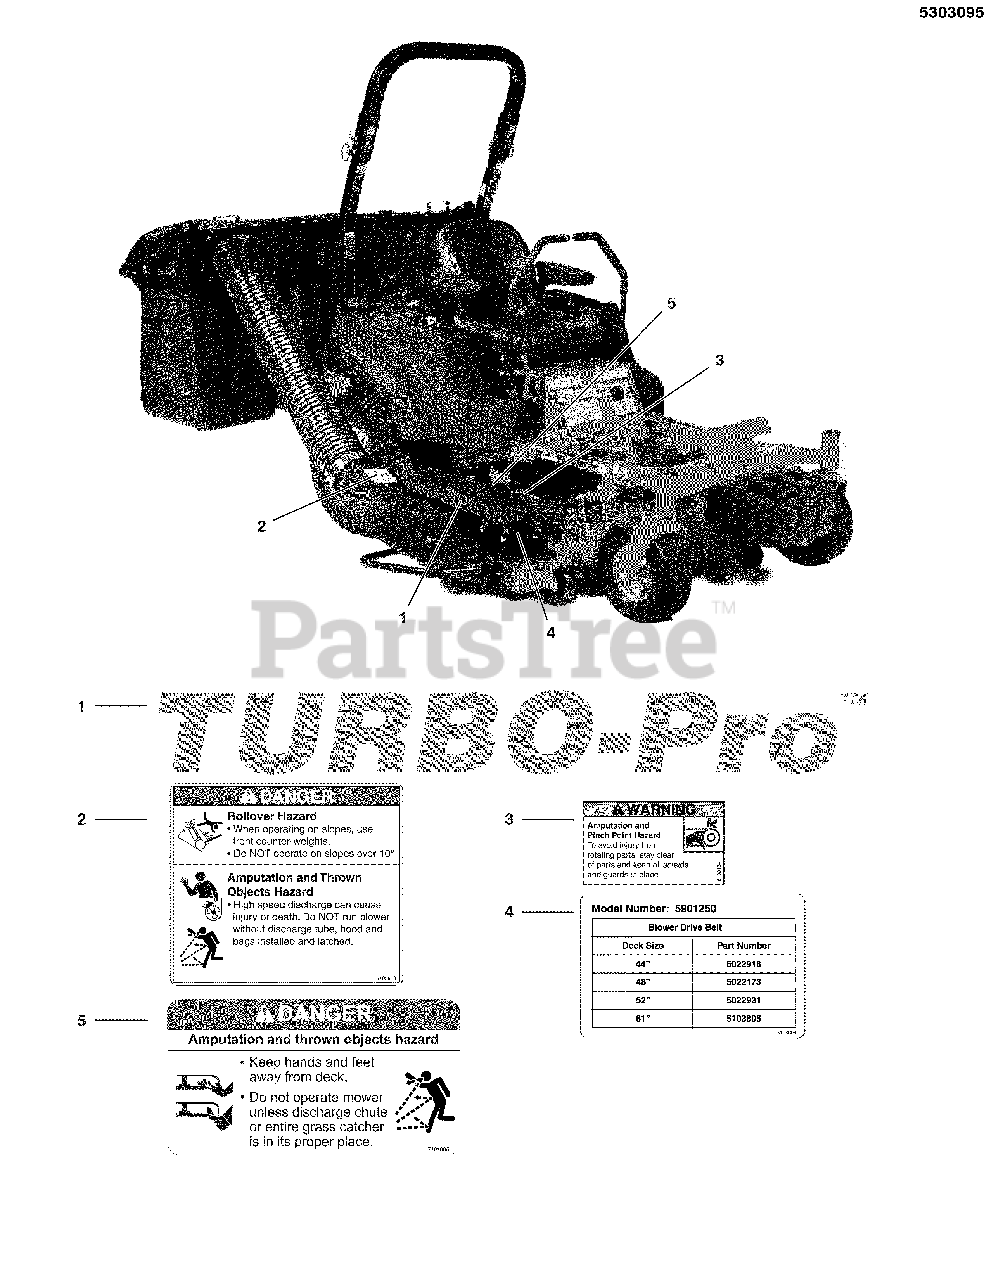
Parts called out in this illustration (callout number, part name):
1	DECAL, TURBO-PRO
2	DECAL, DANGER, TURBO-PRO
3	DECAL, WARNING, HAND IN BELT, ENG
4	DECAL, BELT, TURBO-PRO, ALL
5	DECAL, DANGER DO NOT OPERATE W/O DEFLECT
